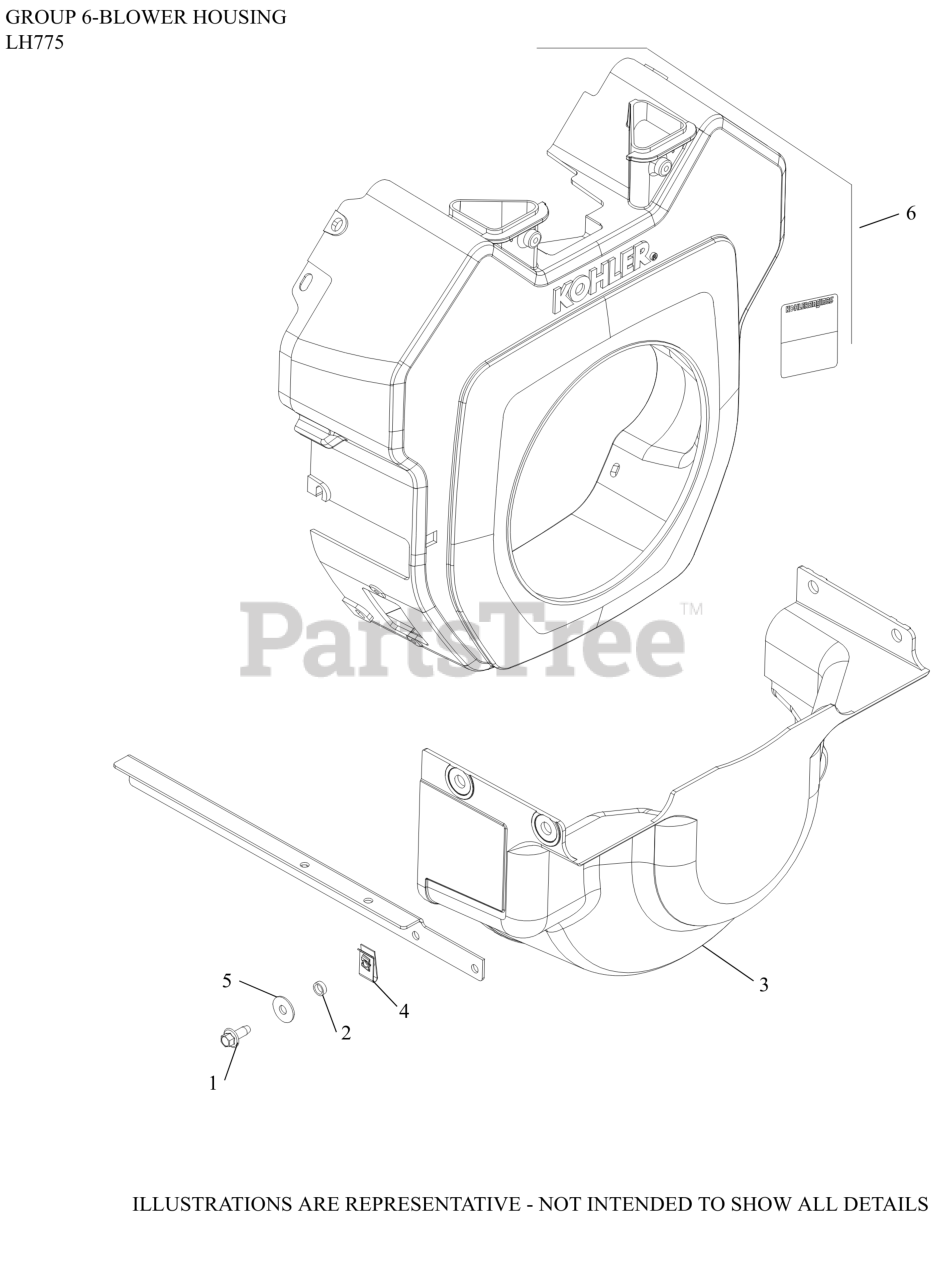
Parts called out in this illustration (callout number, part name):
1	SCREW, THREAD FORMING
3	COVER, ENGINE FLYWHEEL
5	WASHER, FLAT 1/4"
